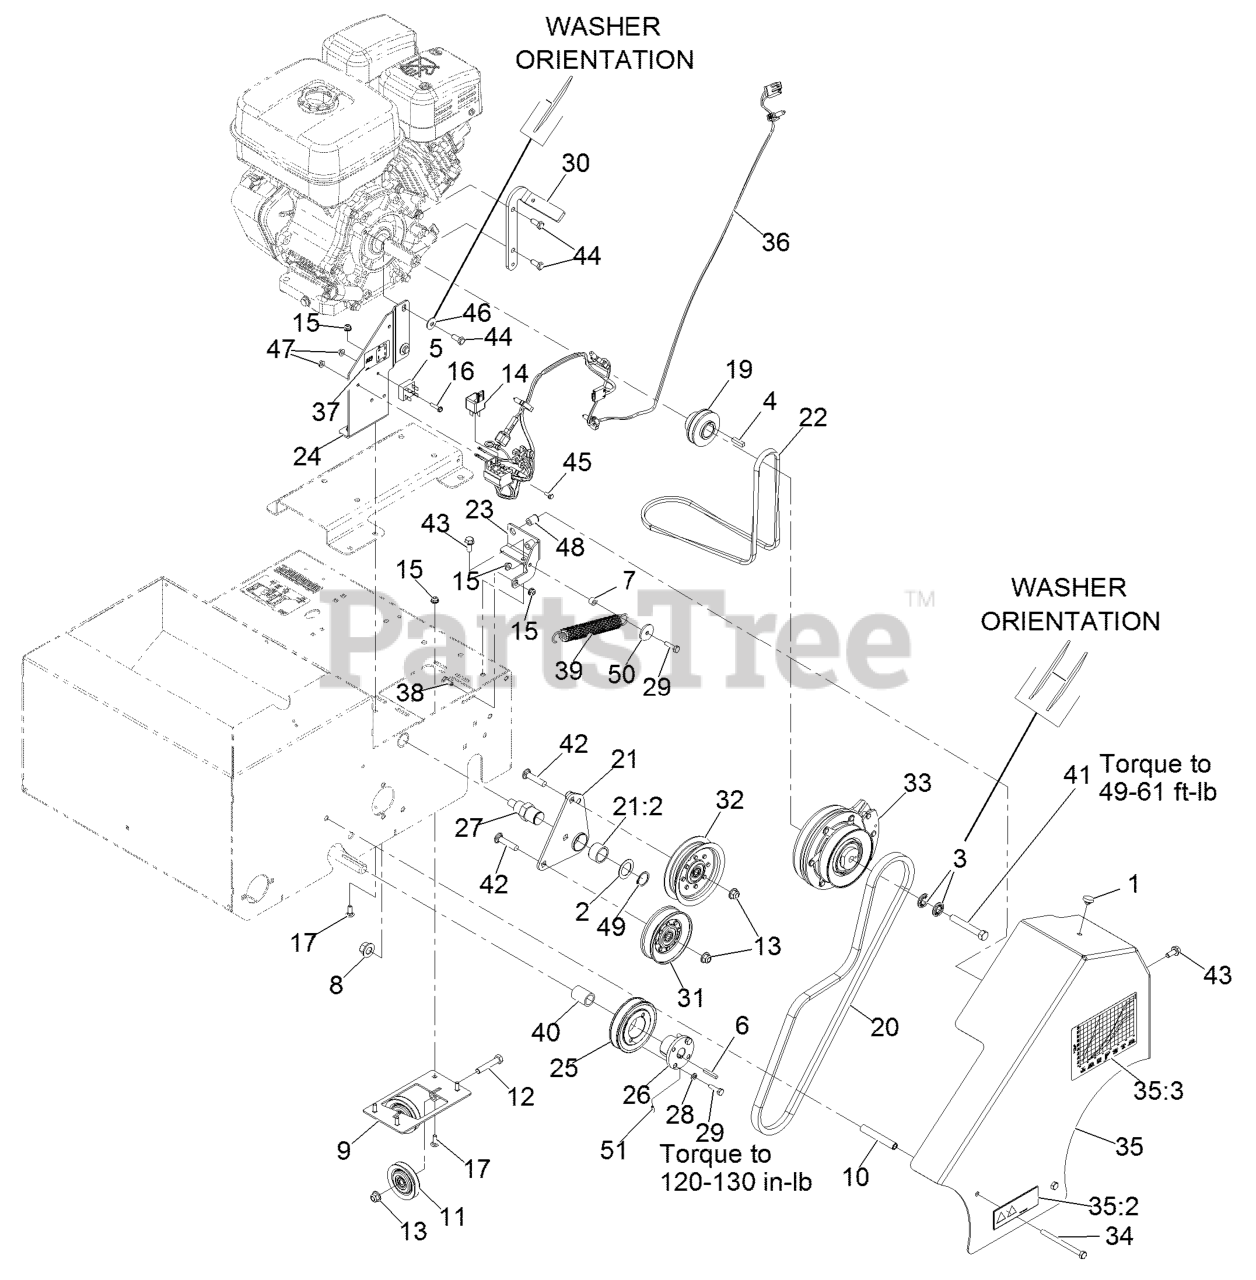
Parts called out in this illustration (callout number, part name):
2	WASHER-SPACER
3	WASHER-SPRING
5	RECTIFIER-BRIDGE
6	KEY-SQUARE
8	Nut-Lock 1/2-13
9	PULLEY-TENSION
10	SPACER-KICKSTAND, LONG
11	PULLEY-IDLER
12	SCREW-HH
13	NUT-HF, NI
16	SCREW-HWH
17	BOLT-CARR
19	PULLEY-MULE DRIVE
20	BELT-SEEDER, CLUTCH
21	IDLER ARM ASM
21:2	BUSHING
22	BELT-MULE DRIVE
23	BRACKET-SPRING
24	SUPPORT-ENGINE
26	BUSHING-TAPER LOCK
27	PIVOT-IDLER
28	SCREW-HH
29	SCREW-HH
30	STOP-CLUTCH
31	PULLEY-IDLER V
32	PULLEY-IDLER FLAT (4.06-I
33	CLUTCH-ELECTRIC
34	SCREW-HH
35	BELT GUARD ASM
35:2	DECAL-DANGER
35:3	DECAL-GRAPH, SEED
36	HARNESS-SLICER/SEEDER
37	Decal-Bridge Rectifier
38	SCREW-HH
39	SPRING-EXTENSION
41	SCREW-HH
42	SCREW-CARR
43	SCREW-HHF
44	SCREW-HH
45	SCREW-HWH
46	WASHER-BELLEVILLE
47	NUT-LOCK, FLANGE
48	NUT-CLINCH
49	RING-RETAINING
50	WASHER
51	SCREW-SET, HS
